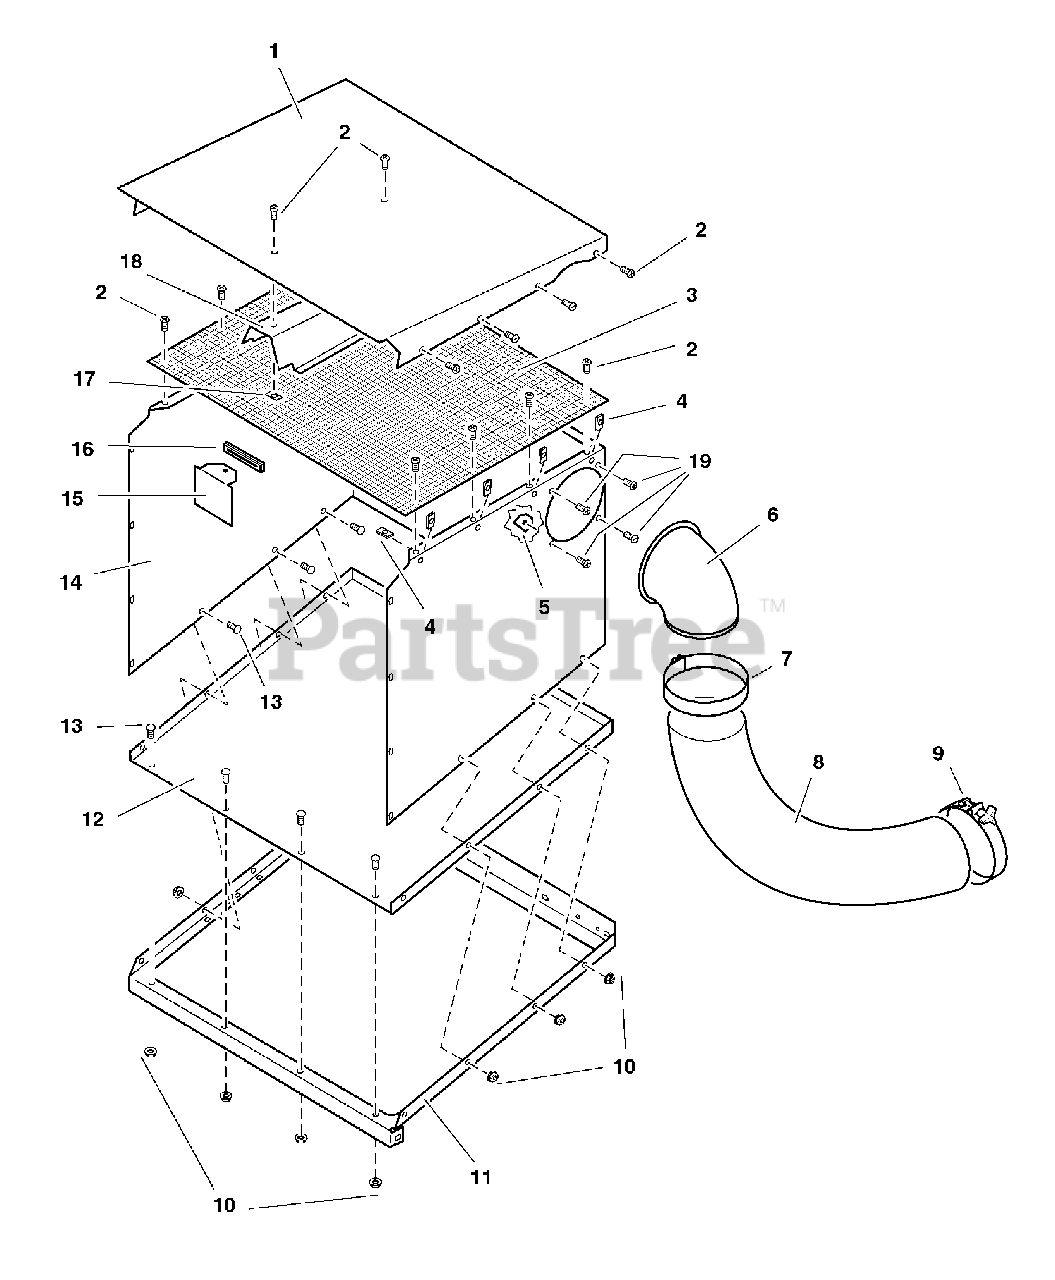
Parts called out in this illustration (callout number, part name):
2	PHILIPS PAN HEAD SCREW, 14 x 1/2
4	TINNERMAN CLIP
5	INLET CLAMP
7	HOSE CLAMP, Upper
8	HOSE, FLEXIBLE, 7" DIA. X 58"
9	HOSE CLAMP, Lower
10	NUT, Hex, Flange, 1/4-20
11	BASE FRAME
12	BOX BOTTOM
13	CARRIAGE BOLT, 1/4-20 x 5/8
14	BOX BACK & SIDES
15	FULL GAUGE
17	TINNERMAN NUT
18	SCREEN SUPPORT
19	PHILIPS PAN HEAD SCREW, 14 x 3/4
